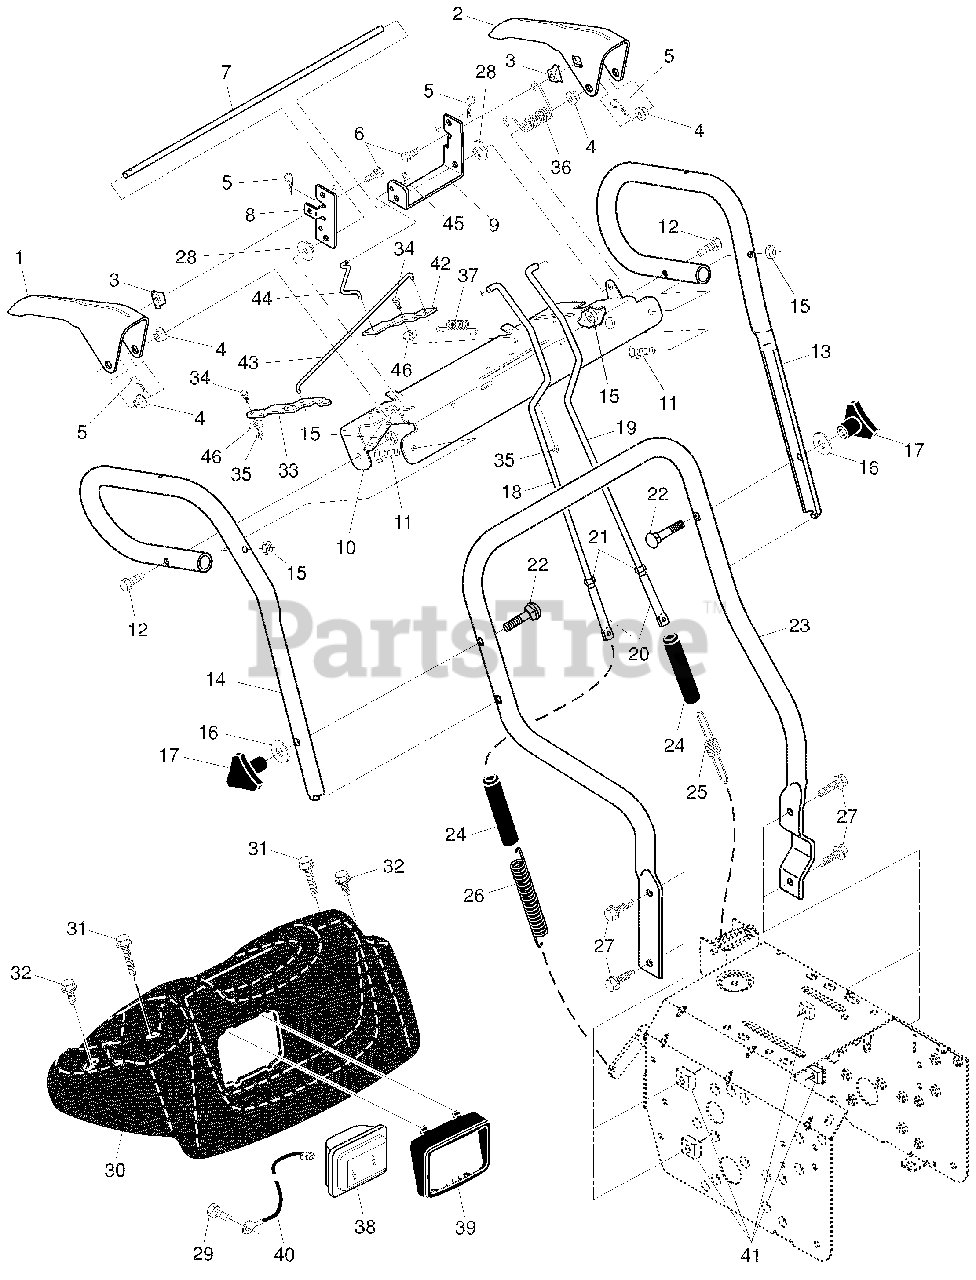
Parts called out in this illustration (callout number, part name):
1	Lever, Auger Control, RH
2	Lever, Traction Drive Control, LH
3	Nut, Cage 1/4-20
4	Bushing, Flange
5	Retainer, Hairpin
6	Screw, Hex Head 1/4-20 x 3/4
7	Rod, Interlock
8	Arm, Impeller Rod
9	Arm, Traction Rod
10	Panel, Control
11	Screw, Hex Head 5/16-18 x 1-1/2
12	Screw, Hex Head 5/16-18 x 1-3/4
13	Handle Tube, LH
14	Handle Tube, RH
15	Nut, Lock 5/16-18
16	Washer, Flat 3/8
17	Knob, Handle
18	Rod, Auger Control
19	Rod, Traction Control
20	End, Control Rod
21	Nut, Hex, Jam 5/16-18
22	Bolt, Carriage 3/8-16 x 2-1/4
23	Handle Tube, Lower
24	Sleeve, Spring
25	Spring, Traction Drive
26	Spring, Auger Control
27	Screw, Hex Head 3/8-16 x 1
28	Bushing, Pivot Lever
29	Screw, Headlight Ground Wire to Blower Housing
30	Console, Panel
31	Screw, Hex Head, Tapping #10-24 x 1-1/4
32	Screw, Hex Head, Tapping #10-24 x 1/2
33	Latch, Interlock
34	Bolt, Shoulder
35	Nut, Lock 1/4-20
36	Spring, Torsion
37	Spring, Interlock
38	Headlight, Halogen
39	Bezel, Headlight
40	Harness, Headlight
41	Nut, Cage 3/8-16
42	Lever, Interlock
43	Rod, Latch, Interlock
44	Rod, Arm, Interlock
46	Washer, Friction
